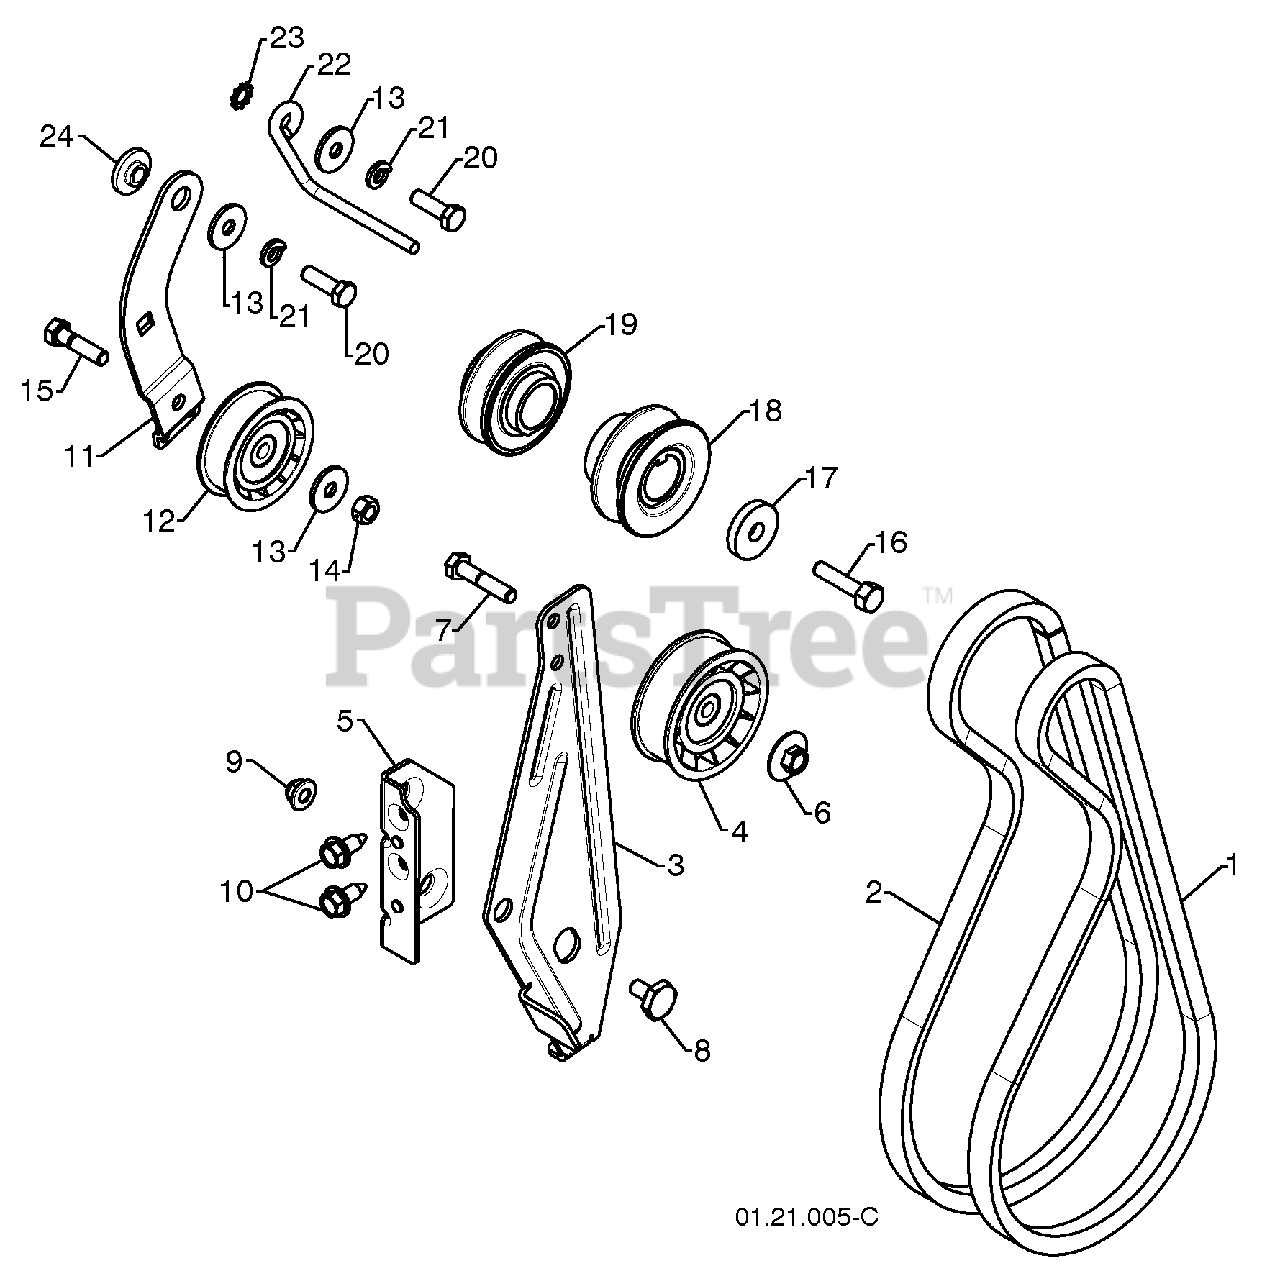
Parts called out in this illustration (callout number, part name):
1	IMPELLER BELT
2	TRACTION BELT
3	IDLER ARM BRACKET
4	IDLER PULLEY
5	IDLER BRACKET
6	NUT 5/16-18
7	SCREW 5/16-18 X 1.50
8	SHOULDER BOLT 5/16-18 X .50
9	NUT 5/16-18 NYLOCK
10	SCREW 5/16-18 X .625
11	TRACTION IDLER BRACKET
12	TRACTION PULLEY
13	WASHER
14	NUT 5/16-18
15	SCREW 5/16-18 X 1.25
16	SCREW 3/8-24 X 1.375
18	PULLEY ENG IMPELLER
19	PULLEY ENG TRACTION
20	SCREW 5/16-24 X 1.00
21	LOCKWASHER 5/16
22	BELT GUIDE
23	LOCKWASHER 5/16
24	IDLER BUSHING
